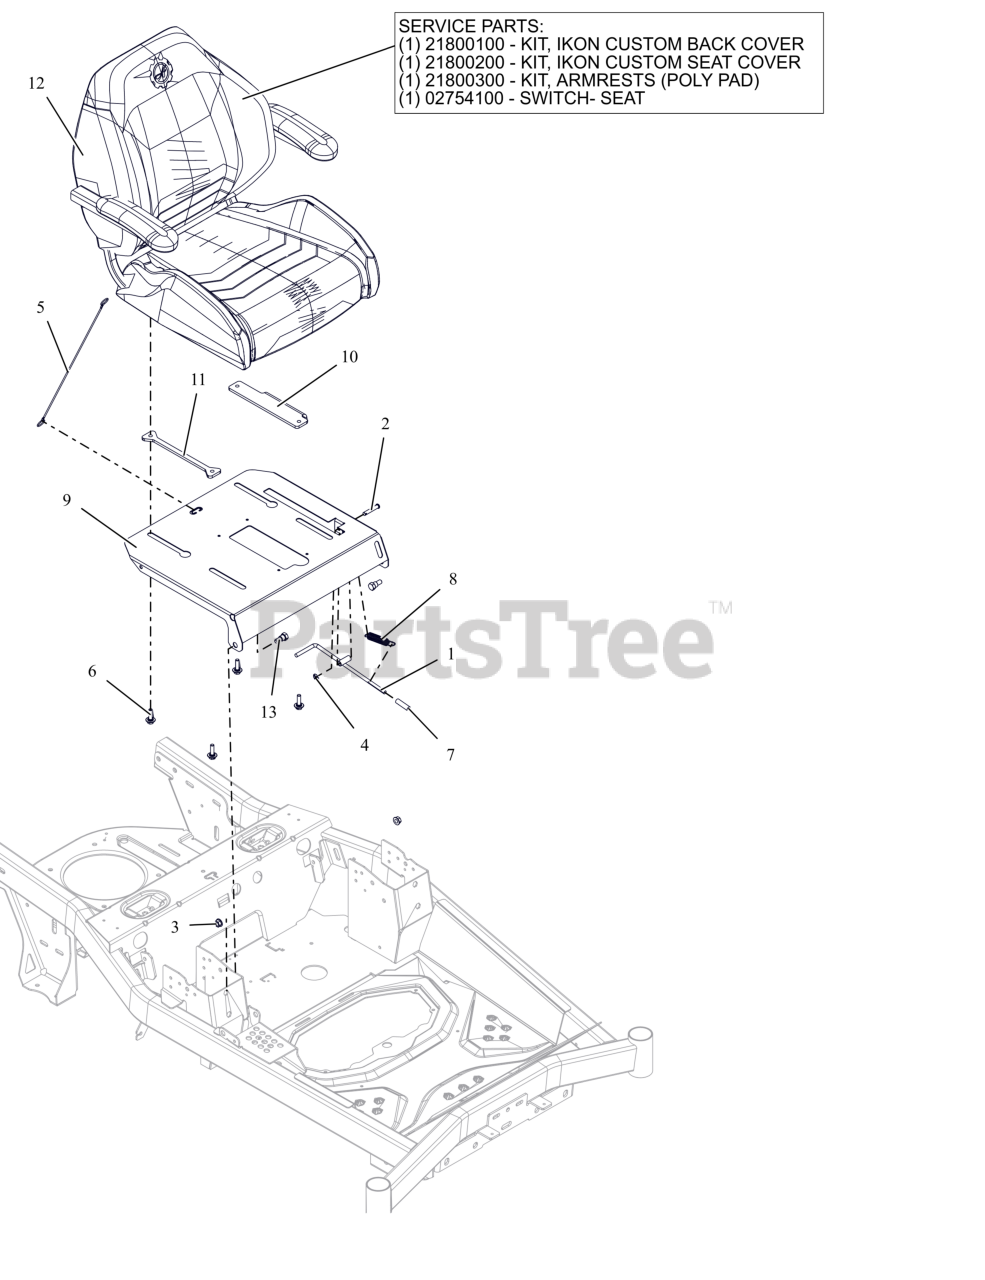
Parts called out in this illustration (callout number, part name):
1	WLDMT, LATCH SEAT (BLACK)
2	PIN, CLEV .309X1.75 ZCC
3	NUT-LK-CTR-FLG .375-16 GF ZCC
4	NUT-PUSH .312
5	LANYARD, SEAT CABLE .093X19.5
6	BLT, SHLDR .31-18 X .100
7	GRIP, BLACK RD-.312X1.50
8	SPRG, EXTENSION .063 X .653 X 2.755
9	PLATE-SEAT
10	PLATE- SEAT ADJUSTER
11	PLATE, ADJ SEAT SLIDE (BLACK)
12	SEAT- IKON 2023 (WOOD)
12	KIT - IKON CUSTOM BACK COVER
12	KIT - IKON CUSTOM SEAT COVER
12	KIT - ARMRESTS (POLY PAD)
12	SWITCH- SNAP MTG N.O.
13	BLT-SHLDR .50X.38 ZCC
